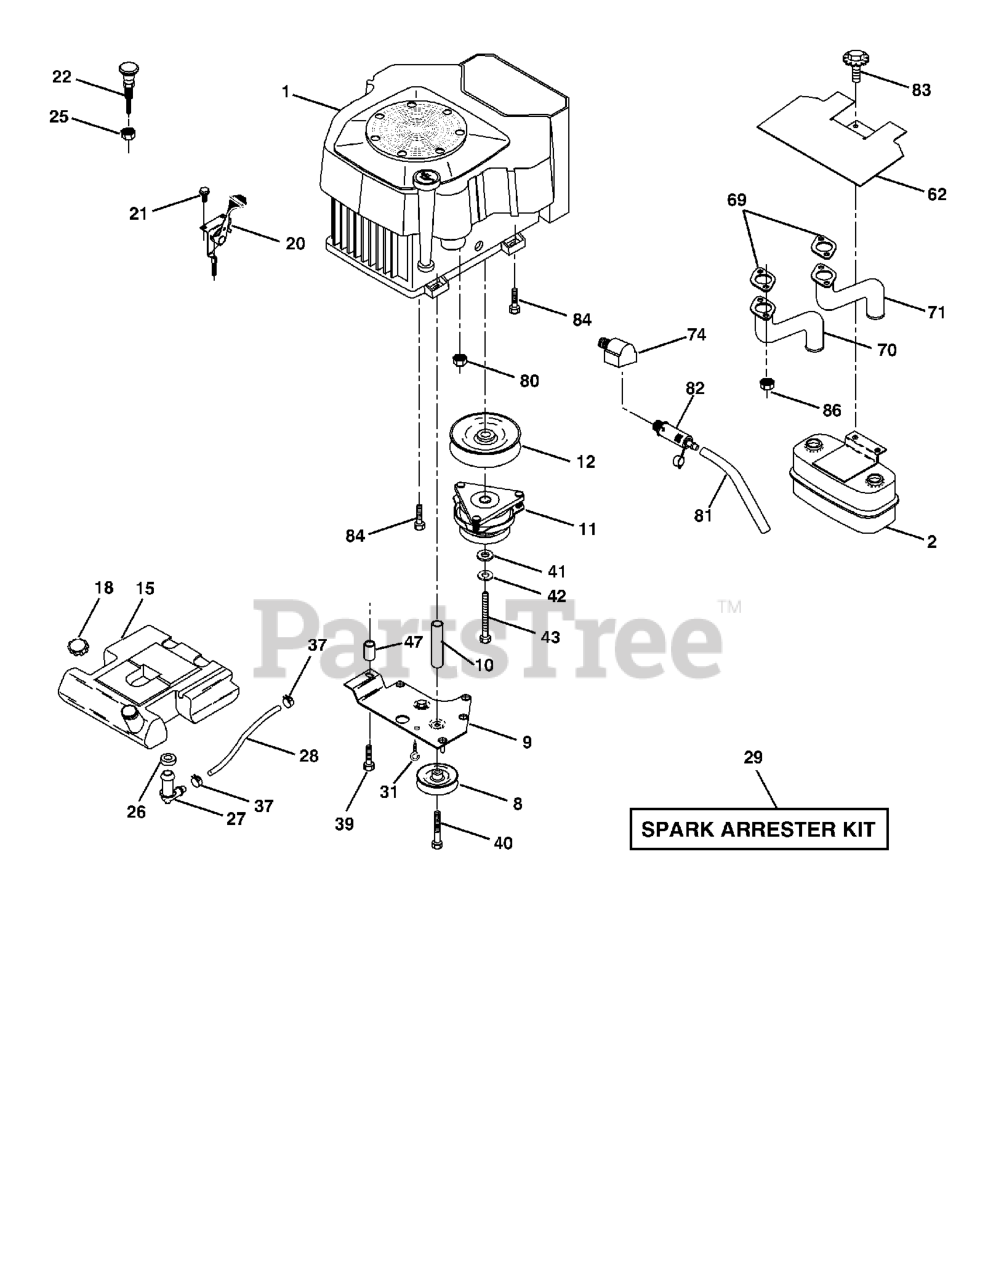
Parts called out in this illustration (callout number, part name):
2	MUFFLER.TWIN.CYL.LOW.TONE
8	RP.IDLER GROOVED
9	KEEPER ASM BELT ENGINE
10	BUSHING
11	CLUTCH MZ ZTR GT.48/54"1.125"
12	PULLEY ENG VGT ELECT CLUTCH
15	TANK.FUEL.5.0 LEFT.FILL.YTGT
18	TANK CAP
20	THROTTLE CONTROL
21	SCREW
22	CHOKE CONTROL
25	Nut Keps 3/8 - 24 UNF
26	BUSHING OUTLET T
27	STEM FUEL TANK
28	HOSE
29	SPARK ARREST
31	PUSH CLIP
37	HOSE CLAMP
39	SCREW TT 3/8-16X2-1/4 UNC
40	Screw TT 3/8-16 x 4 unc
41	WASHER
42	LOCKWASHER
43	BOLT HEX 7/16-20 X 3.75 GR. 5
47	BUSHING
62	RP SHIELD HEAT MUFFLER
69	GASKET.EXHAUST.KOHL.CV18-CV26
70	TUBE EXHAUST LH
71	TUBE.EXHAUST.LV675.COMMAND.RH
74	ELBOW STREET BRASS
80	FLANGE NUT
81	TUBE, DRAIN OIL ASM.
82	PLUG DRAIN OIL EASY
83	BOLT.5/16-18UNCX3/4 W/SEMS.BLK
84	SCREW 3/8-16 X 1-1/2
86	NUT.HEX.FLANGE.TOPLOCK
